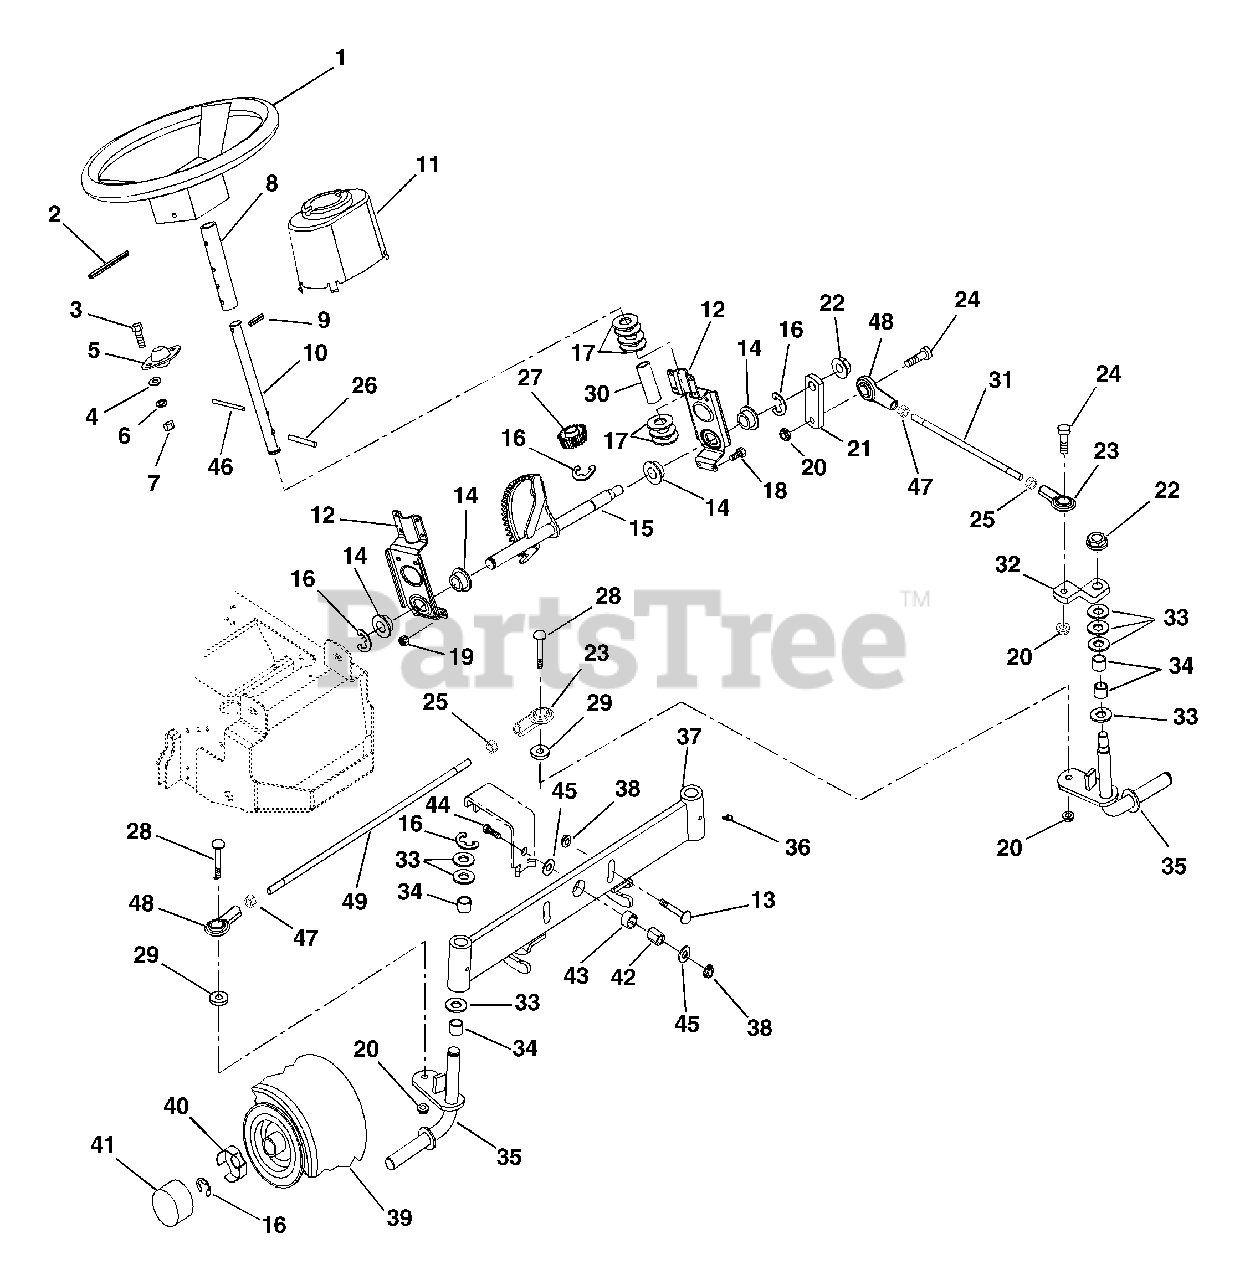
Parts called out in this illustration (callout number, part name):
1	STEERING WHEEL 13"
2	PIN-ROLL .250X1.75
3	@BLT-HEX .31-18X.75 GR5 YWZC
4	@WSHR-FL-STL.312X.734X.065 YWZ
5	BRG-FLG .751X2 HOLESX.81
6	WSHR-LK .312X.097 HVY YWZC
7	@NUT-HEX .31-18 YWZC
8	TUBE .754 X .999 X 5.00
9	PIN-ROLL .250X1.000
10	COLUMN, STEERING
11	CONE- STEERING COLUMN
12	BRACKET-STEERING GEAR
13	@BLT-HEX .38-16X1.50 GR5 YWZC
14	BSHG-FLG .750X1.093X.625X1.375
15	GEAR, STEERING
16	RG-RTNG-EXT .750X.050
17	WSHR-FL-STL.755X1.375X.062YWZC
18	@BLT-HEX .25-20X.75 GR5 YWZC
19	@NUT-LK-CTR .25-20 YWZC
20	@NUT-LK-TOP-FLG .38-16 YWZC
21	ARM, STEERING ROD
22	NUT-LK .563-18 GR5 YWZC
23	ROD END, .38 RH
24	BLT-BTHD .38-16X1.25 GR5
25	NUT-JAM .375-24 YWZC
26	PIN .249X1.125 DRIV-LOK SP
27	PINION GEAR-STEERING
28	@BLT-HEX .38-16X1.75 GR5 YWZC
29	BSHG-SLV .377X.624X.370
30	BSHG-SLV .753 X 2.00 SELF LUB.
31	LINK, DRAG
32	ARM - STEERING SPINDLE
33	WSHR-FL-STL.755X1.375X.062YWZC
34	BSHG-SLV .750X.814X .750 BRZ
35	SPINDLE ASY, L.H
35	SPINDLE ASY., R.H
36	FTG-LUBE .25-28X.256 YWZC
37	AXLE, FRONT
38	@NUT-LK-CTR .38-16 YWZC
39	TIRE/WHEEL ASSY 15 X6.00-2 PLY
39	WHEEL W/BEARINGS
39	BSHG .75 BORE
39	FTG- LUBE .25-28X.97
39	BRG-BALL .752X1.380X.500
40	SPINDLE CUP
41	HUB CAP
42	BSHG-SLV .377X.623X.775 HEX
43	BSHG-SLV .626X1.000X.524 HEX
44	@BLT-HEX .38-16X1.75 GR5 YWZC
45	WSHR-FL-STL .380X1.50X.125YWZC
46	PIN-ROLL .188X1.13
47	NUT-JAM .375-24 LH YWZC
48	END, ROD-.38 LH
49	ROD, TIE
